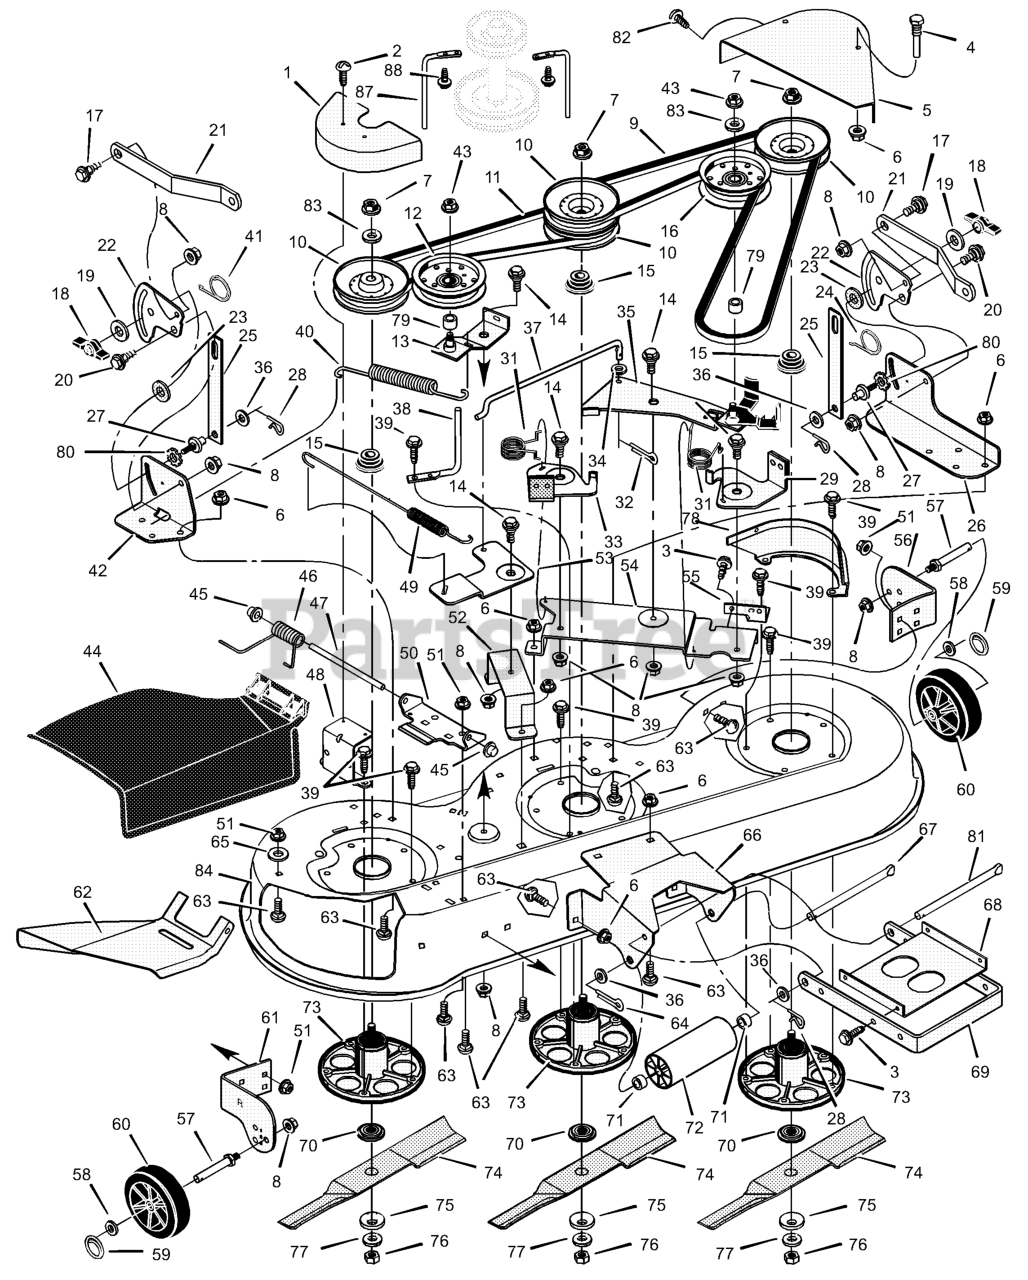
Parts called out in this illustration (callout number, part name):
1	Cover, Right Pulley
2	Screw
4	Guide, Belt
5	Cover, Left Pulley
6	Nut, Hex
7	Nut, Flange
8	Nut, Flange
9	Belt, Primary
10	Pulley
11	Belt, Secondary
12	Pulley, Idler
13	Arm, Idler
14	Bolt, Shoulder
15	Spacer, Pulley
16	Pulley, Idler
17	Bolt, Shoulder
18	Knob
20	Bolt, Shoulder
21	Bracket, Rear Suspension
22	Plate, Suspension
23	Pad, Friction
25	Link, Lift
26	Bracket, Left Lift
27	Pin, Hanger
28	Pin, Hair
29	Brake Assembly, Left
32	Pin, Cotter
33	Brake Assembly, Right
34	Washer
35	Idler, Arm
37	Link, Bell Crank
38	Guide, Belt
39	Screw
40	Spring, Extension
41	Spring, Torsion
42	Bracket, Suspension
43	Nut
44	Deflector, Chute
45	Push On Cap
46	Spring, Torsion
47	Rod, Deflector
48	Bracket, Cover
49	Spring, Extension
50	Bracket, Hinge
51	Nut, Flange
52	Bracket, Bell Crank
53	Crank, Bell
54	Plate, Brake Arm
55	Bracket, Brake Plate
56	Bracket, Left Gauge Wheel
57	BOLT, Gauge Wheel
59	Ring, Locking
60	Wheel, Gauge
61	Bracket, Right Gauge Wheel
62	Deflector, Inside
63	Bolt, Carriage
64	Pin, Cotter
66	Bracket, Front Deck
67	Rod, Hanger
68	Stiffener
69	Bracket, Suspension
70	Adapter, Blade
73	Housing, Jackshaft
75	Washer, Belleville
78	Bracket, Pulley Cover
81	Rod, Hanger
83	Washer
84	Housing, Blade
87	Guide, Belt
88	Screw
